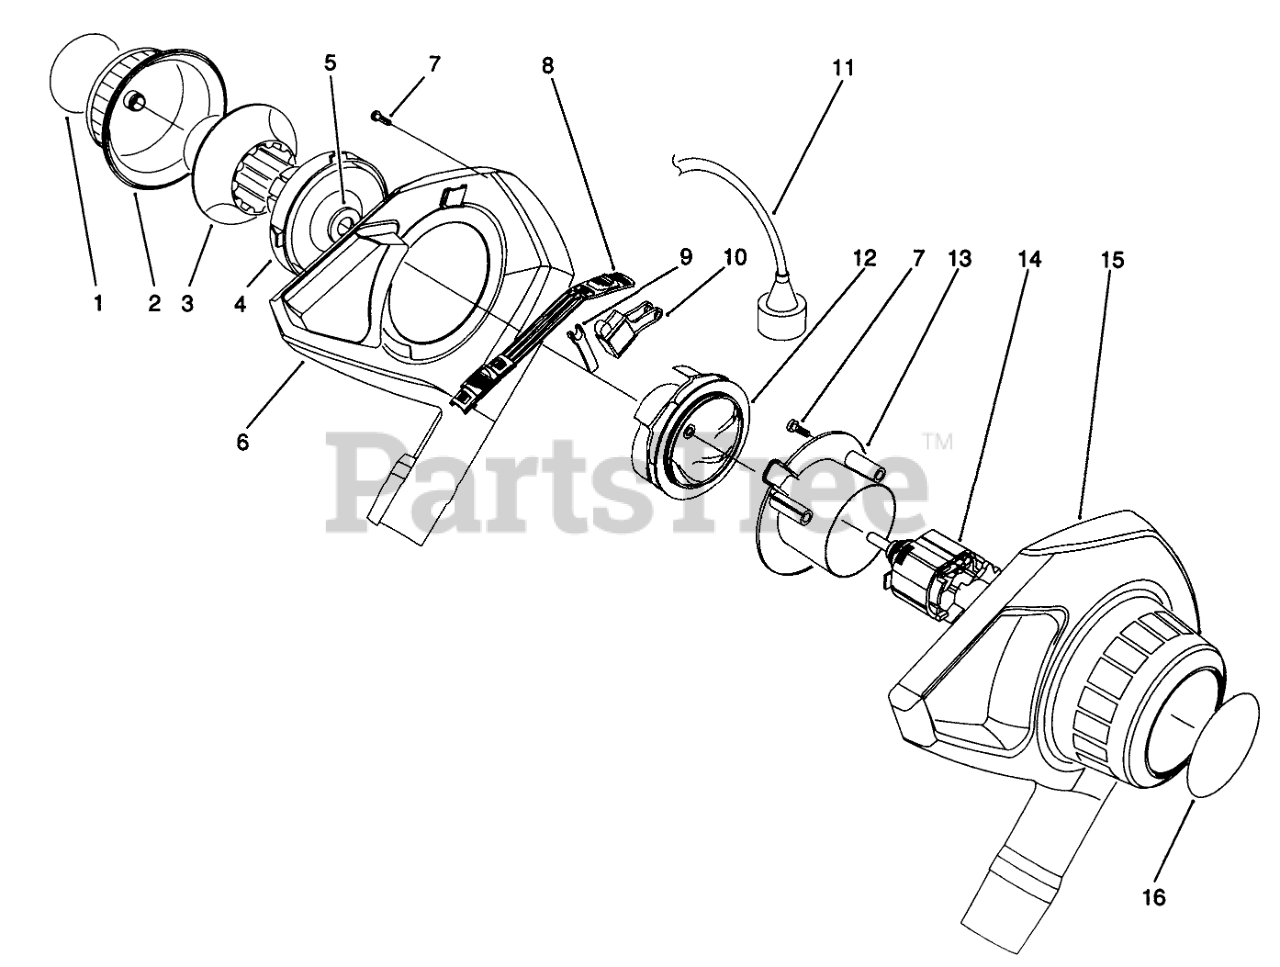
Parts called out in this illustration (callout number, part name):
1	DECAL, 700 CHOKE
2	CHOKE COVER, 600/700
3	MID BL-RING CHOKE
4	MID BL-BASE CHOKE
5	Clip-Retainer
6	HOUSING ASSY, RH
7	Screw
8	SWITCH BAR, 600/700
9	MID BL-ACTUATOR
10	Switch
11	POWER SUPPLY CORD
12	Impeller Assembly
13	Plate-Retaining
14	Motor
15	HOUSING, LH
16	SERIAL DECAL 700
